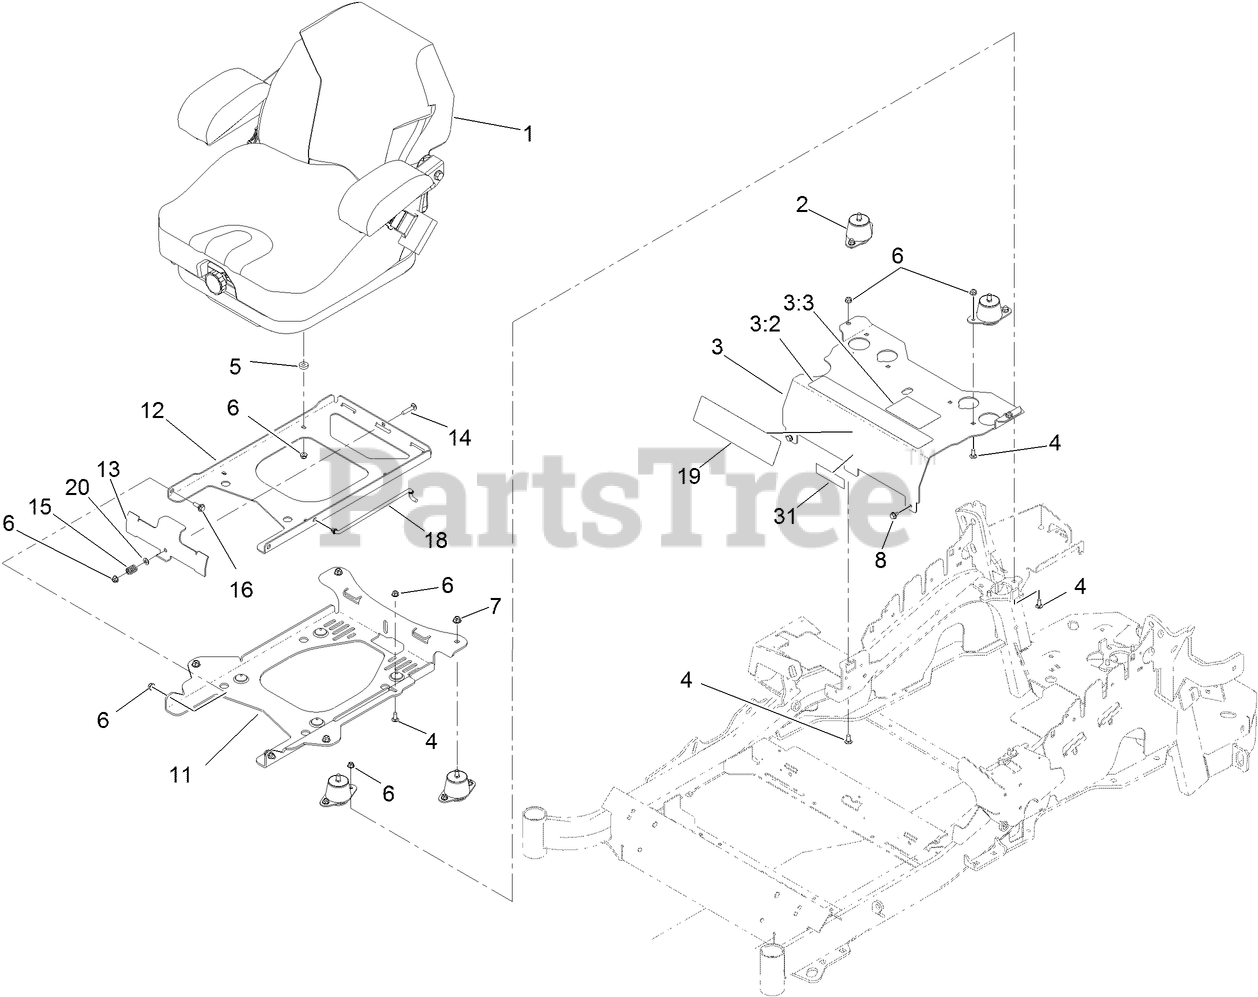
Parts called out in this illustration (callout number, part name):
1	SUSPENSION SEAT ASM
2	ISOLATOR-SEAT
3	MOUNT-SEAT
3:2	DECAL-CONSOLE
3:3	DECAL-SERVICE AID
4	SCREW-CARR
5	SPACER-PIN, MOUNTING
6	NUT-HF, NI
7	NUT-HF, NI
8	SCREW
11	PLATE-TILT, SEAT SUPPORT
12	PLATE-FRAME, SEAT
13	PLATE-LATCH, SEAT
14	BOLT-CARR
15	SPRING-COMPRESSION
16	SCREW-SHOULDER
18	ROD-PROP
20	WASHER-PLAIN
31	DECAL-PROPANE
